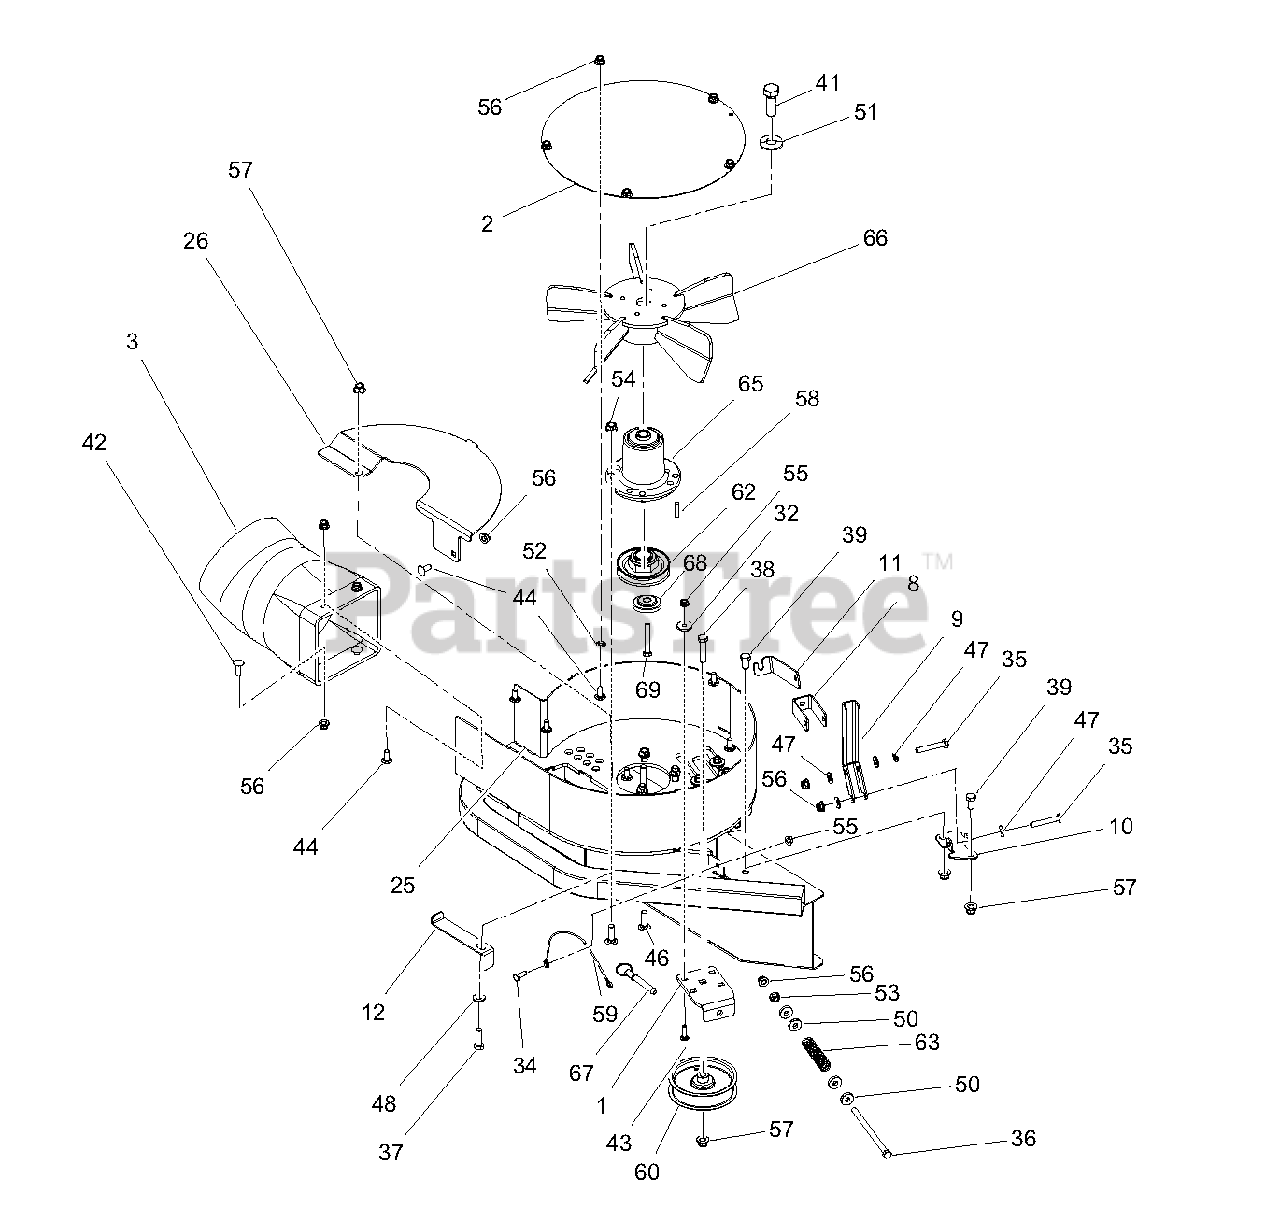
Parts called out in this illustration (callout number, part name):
1	BRKT, ADJUSTABLE IDLER
2	COVER, BLOWER-BLACK
3	ADAPTER, HOSE
8	LINK, IDLER RELEASE-BLACK
9	LEVER, IDLER RELEASE-BLACK
10	MOUNT, IDLER RELEASE LEVER-BLK
11	LOCK, IDLER RELEASE LEVER-BLACK
12	FINGER BELT-BLACK
25	WELDMENT, BAGGER BLOWER-RED
26	COVER, BOTTOM - BLK
32	BSHG, FLG .265 X .477 X .375 X 1.00
34	BLT-HEX .25-20 X .75
35	BLT-HEX .31-18 X 2.00
36	BLT-HEX .31-18 X 5.50
37	BLT-HEX .38-16 X 1.25
38	BLT-HEX .38-16 X 1.75
39	BLT-HEX .38-16 X .75 GR5 YWZC
41	BLT, HEX .62-18 X 1.75
42	BLT-RDHDSQSHNK .31-18 X 1.00
43	BLT-RDHDSQNK .25-20 X 1.00
44	BLT-RHDSSQNK .31-18 X .75
46	BLT-RDHDSQNK .38-16 X 1.25
47	WSHR-FL-NYL .375 X .75 .060
48	WSHR-FL-STL .406 X .812 X .065
50	WSHR-FL-STL .328 X .87 X .179
51	WSHR, BLVL .63 X 1.625 X .14
52	NUT, PUSH .312
53	NUT-SPNLK-FLG .312-18
54	NUT, LK-CTR-FLG .38-16
55	NUT, LK-TOP-FLG .25-20
56	NUT-LK-NYL-FLG .31-18
57	NUT-LK-NYL-FLG .38-16
58	KEY SQUARE .25 X .25 X 1.00 RC 40-50
59	LANYARD, 12"
60	PULLEY, IDLER 4.00 X .375
62	PULLEY, 1" OD X 3.50" OD-LOW FILM
63	SPRG, COMPRESSION
65	SPINDLE BLOWER ASSEMBLY
66	WLDMT, IMPELLER FAN
67	PIN, SPRING BALL .375 OD X 1.50
68	RETAINER, SHEAVE
69	BLT-HEX .38-16 X 2.75
